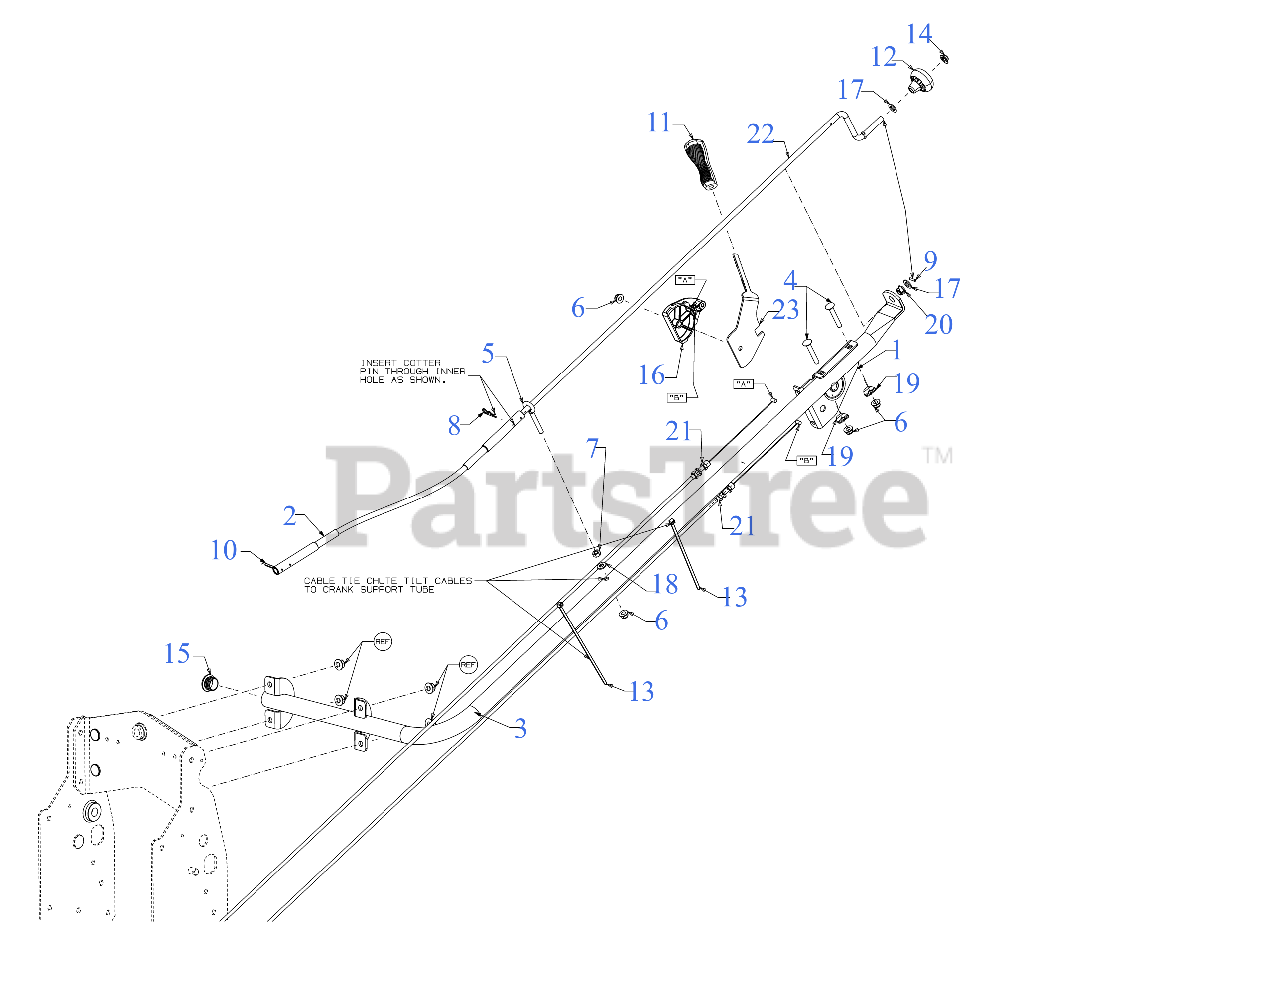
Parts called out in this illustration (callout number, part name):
1	CHUTE TILT BRACKET
2	CHUTE CRANK
3	CHUTE CRANK SUPPORT (POWDER BLACK)
4	BOLT 5/16-18 x 2.00 GR5
5	EYEBOLT 5/16-18 x 3.25
6	FLANGE LOCK NUT 5/16-18
7	HEX NUT 5/16-18
8	INTERNAL COTTER PIN-1/2 DIA
9	ROLL PIN 1/18 DIA
11	HANDLE GRIP
12	SHIFT KNOB
13	7" CABLE TIE
14	PUSH NUT
16	CABLE GUIDE
17	FLAT WASHER
18	FLAT WASHER
19	SADDLE WASHER
20	BUSHING .380 ID
21	CHUTE CONTROL CABLE 74.5"
22	CHUTE CRANK UPPER
23	CHUTE HANDLE TILT (POWDER BLACK)
